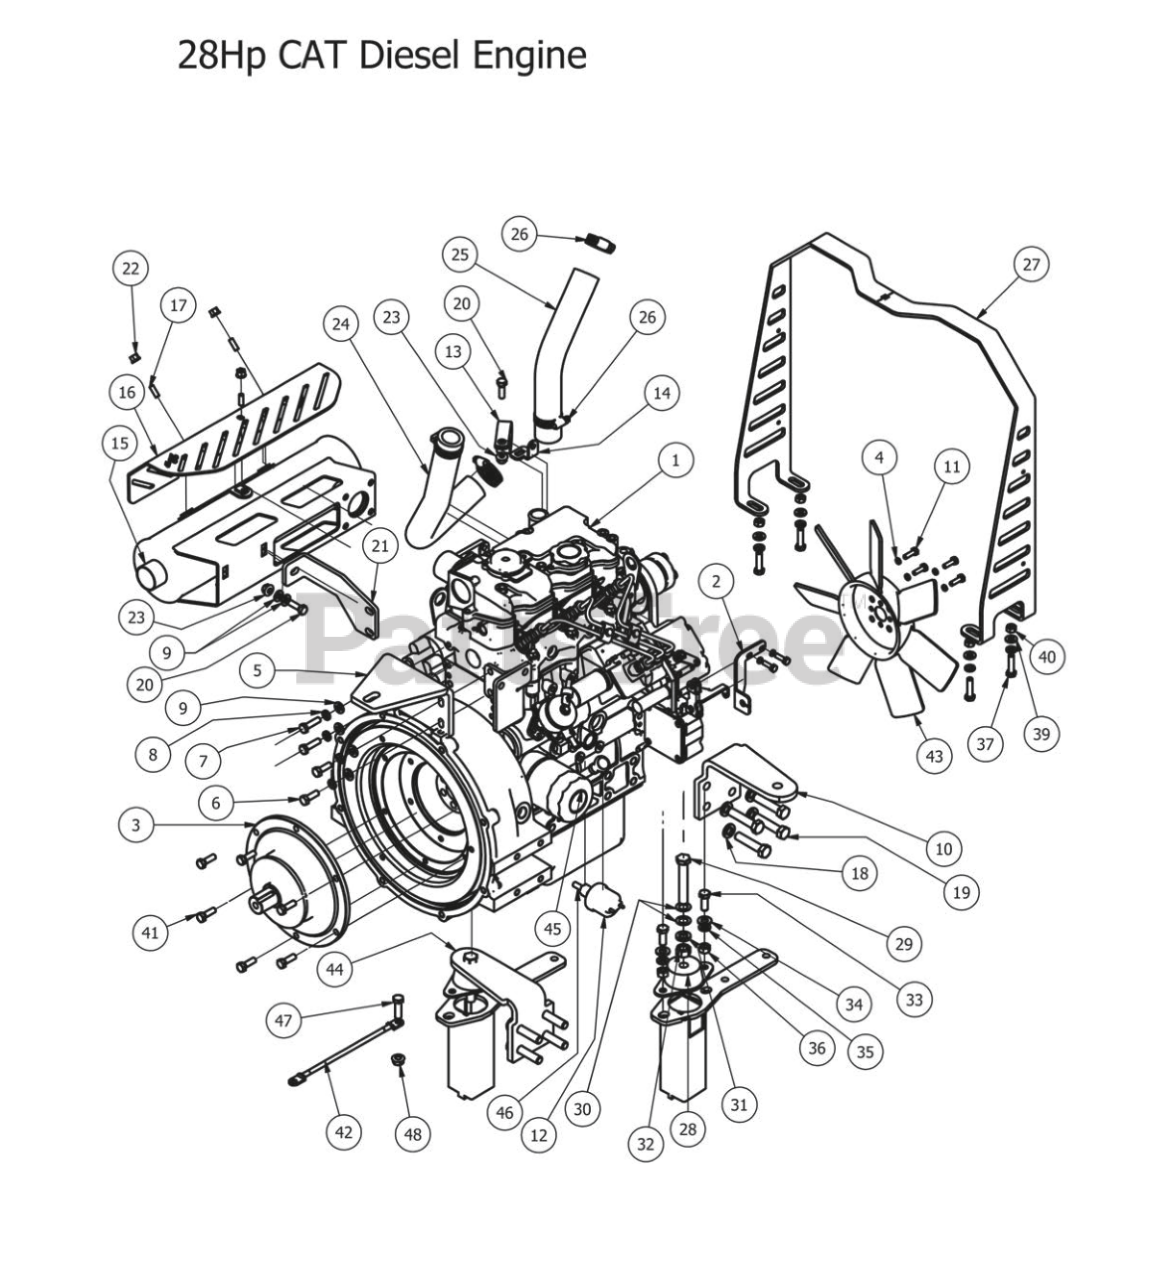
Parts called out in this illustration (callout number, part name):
1	28hp CAT Diesel Engine
2	Diesel Throttle Bracket (4 Tier)
3	Stub Shaft
4	1/4" Lock Washer
5	Air Cleaner Support Diesel
6	M8 x 1.25 x 25mm Hex Head Bolt
7	M8 x 1.25 x 30mm Hex Head Bolt
8	5/16" Lock Washer
9	5/16" Flat Washer
10	Diesel Motor Side Support Right
11	6mm x 20mm Bolt
12	Pressure sender-2012 Gauge and up
13	Diesel Clamp 1 3/4" Vinyl
14	Diesel Radiator Hose Clamp Bracket
15	28/35hp Caterpillar Muffler
16	Diesel Muffler Guard (28hp)
17	1/4" x 3/4" Set Screw
18	1/2" Lock Washer
19	12mm Bolt- Diesel
20	5/16" x 1" Bolt
21	Muffler Brace Diesel
22	1/4-20 Nylon Insert flange Nut
23	5/16" Flange Nut
24	Bottom Radiator Hose for Diesel
25	Top Radiator Hose for Diesel
26	1 1/8" Hose Clamp
27	Hood Holder Diesel
28	Rubber Isolator
29	1/2" x 3" Hex Bolt
30	1/2" Brass Washer
31	1/2" Lock Washer
32	1/2" Hex Nut
33	3/8" x 1" Hex Bolt
34	3/8" Flat Washer
35	3/8" Lock Washer
36	3/8" Hex Nut
37	5/16" x 1 1/4" Hex Bolt
38	5/16" Lock Washer
39	5/16" Flat Washer
41	5/16-18 X 1 Button Head Bolt
42	Starer To Chassis Cable - Diesel
43	Engine Fan - Diesel
44	Diesel Side Motor Mount Left
45	CAT Oil Filter
46	Brass Washer For Weld On Hinge
47	3/8" x 1 1/2" Hex Bolt
48	3/8" Flange Nut
